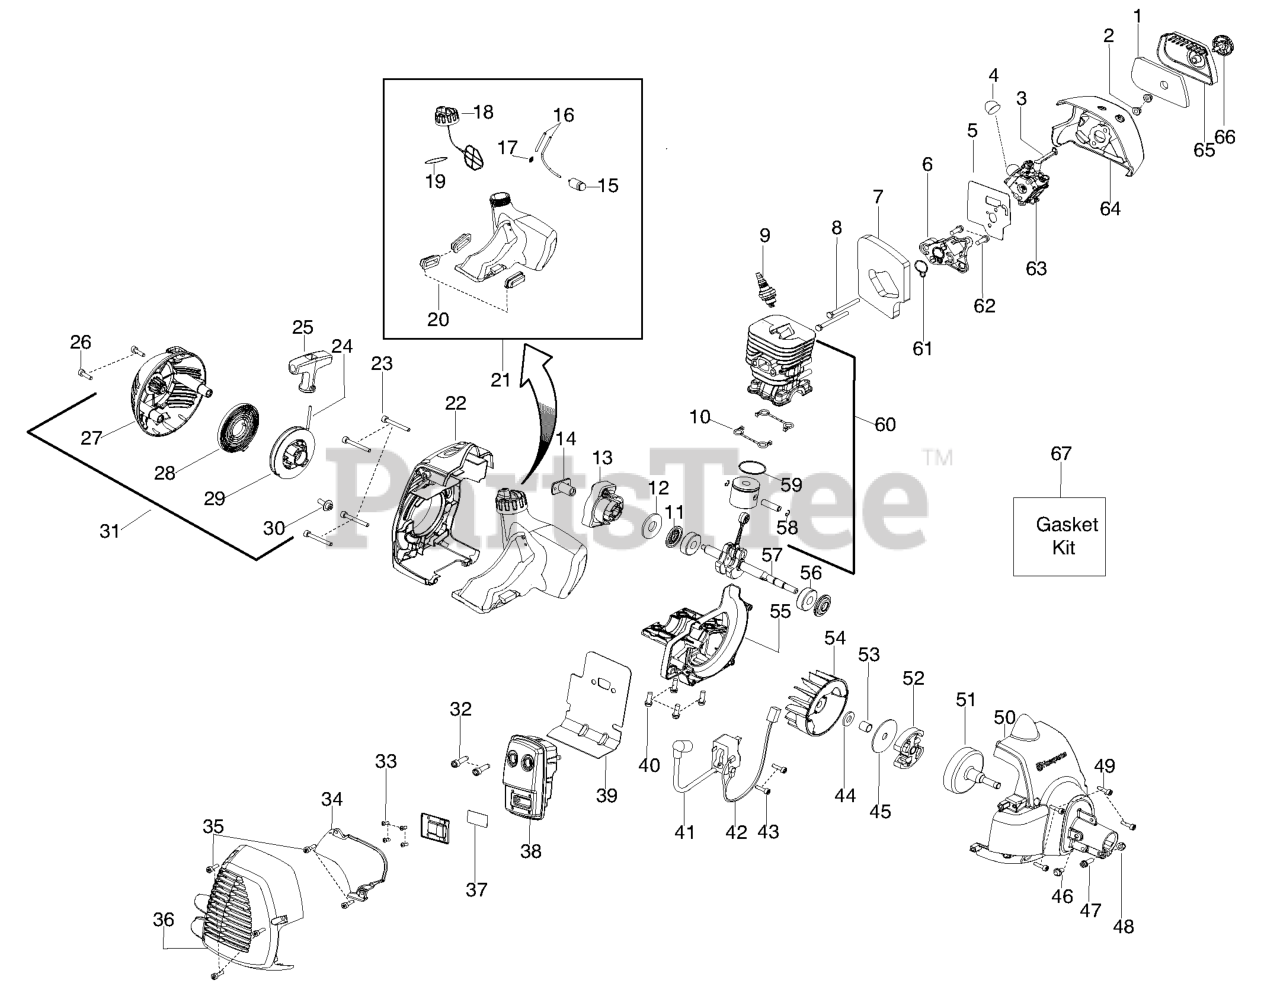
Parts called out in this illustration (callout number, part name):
1	FILTER AIRBOX
3	CHOKE LEVER
4	PURGE BULB ZAMA
5	KIT GASKET CARB 28CC
6	CARB ADAPTOR
7	KIT GASKET 28CC
8	BOLT CARB ADAPTOR
9	Plug - Spark (RCJ-6Y)
10	KIT GASKET 28CC
11	KIT GASKET 28CC
12	Washer
13	Assy - Starter Cup
14	Coupling - Starter
15	FUEL PICK-UP ASSY
16	KIT-LINE(FUEL)
17	FUEL LINE FITTING
18	ASSY-CAP W/RETAINER
19	KIT GASKET 28CC
20	ISOLATOR FUEL TANK
21	KIT FUEL TANK HVA
22	REAR SHROUD
25	STARTER HANDLE GRAY
26	SCREW M5-0.8X30MM
27	STARTER HOUSING
28	%KIT STARTER SPRING
29	KIT STARTER PULLEY
31	ASSY-STARTER HSG.
32	BOLT MUFFLER
33	SCREW-6-19X5/16PLAST PA
34	SHIELD HEAT
35	SCREW M4 X 1.75 PT 16MM
36	GUARD-MUFFLER
37	KIT SPARK ARRESTOR SCREEN
38	KIT MUFFLER LE28
39	KIT GASKET 28CC
40	SCREW-M5-0.8 X 25MM(TAP)
41	IGNITION MODULE MB45
42	ASSY MODULE LEAD WIRE
43	SCREW M4 X .70 TT 16MM
44	WASHER CLUTCH
45	WASHER-CLUTCH
48	LOCKNUT-HEX 10-24
49	SCREW M4 X .70 TT 16MM
50	FAN HSG ASSY
51	Assy - Clutch Drum
52	%KIT CLUTCH ASSY
53	SPACER FLYWHEEL
55	Crankcase - cast
56	BEARING RADIAL BALL (6201)
57	Crankshaft - Assy
58	WRIST PIN RET.
59	RING PISTON
60	Kit - Cyl./Piston
61	KIT GASKET 28CC
62	SCREW-M5-0.8 X 25MM(TAP)
63	Kit - Carb.
64	Airbox
65	COVER-AIR BOX
66	KNOB ASSY AIRBOX COVER
67	KIT GASKET 28CC
